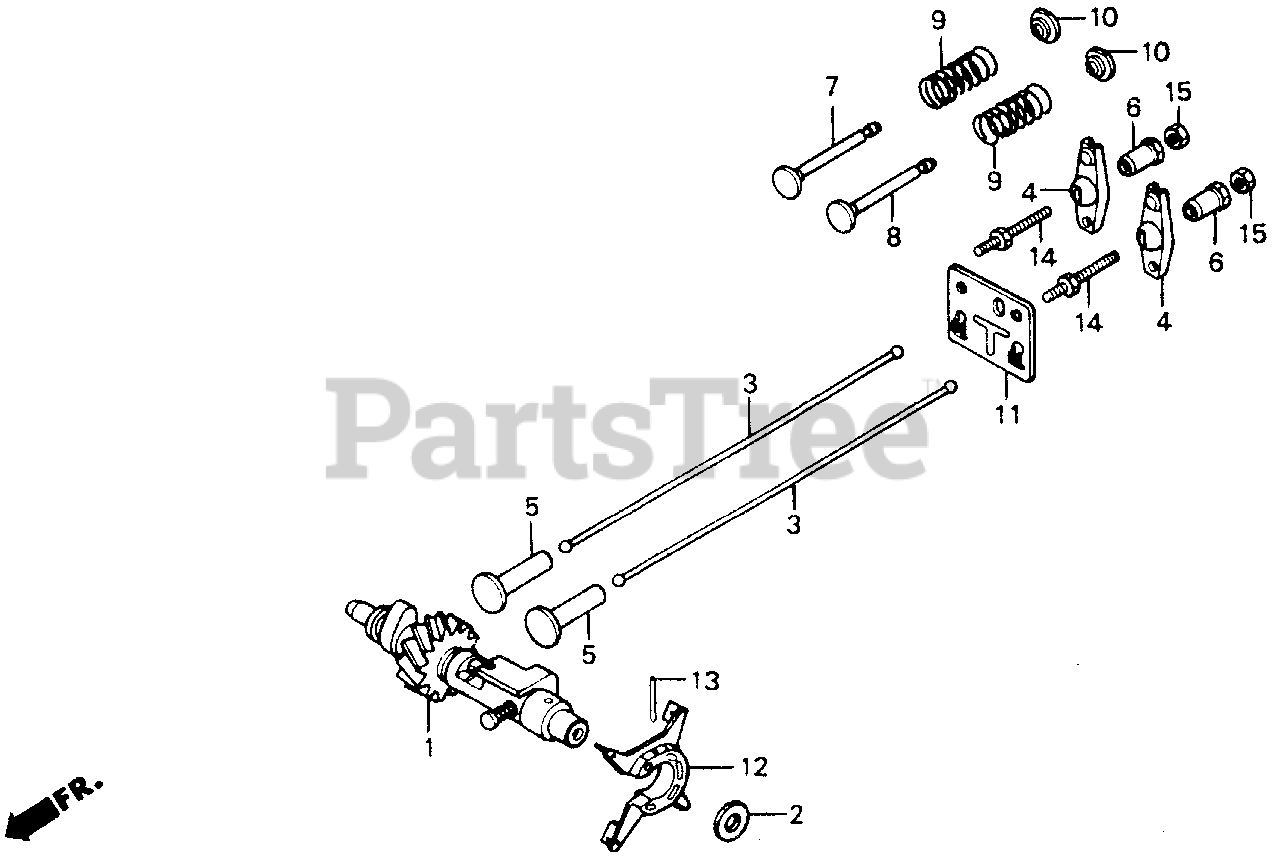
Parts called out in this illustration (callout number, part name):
1	CAMSHAFT ASSY.
2	WASHER, CAMSHAFT SIDE
4	ARM, VALVE ROCKER
5	LIFTER, VALVE (NOT AVAILABLE)
6	PIVOT, ROCKER ARM
7	VALVE, IN. (NOT AVAILABLE)
8	VALVE, EX.
9	SPRING, VALVE
10	RETAINER, IN. VALVE SPRING
11	PLATE, PUSH ROD GUIDE
12	SLINGER, OIL
13	PIN, OIL SLINGER
14	BOLT, PIVOT (8MM)
15	NUT, PIVOT ADJUSTING
